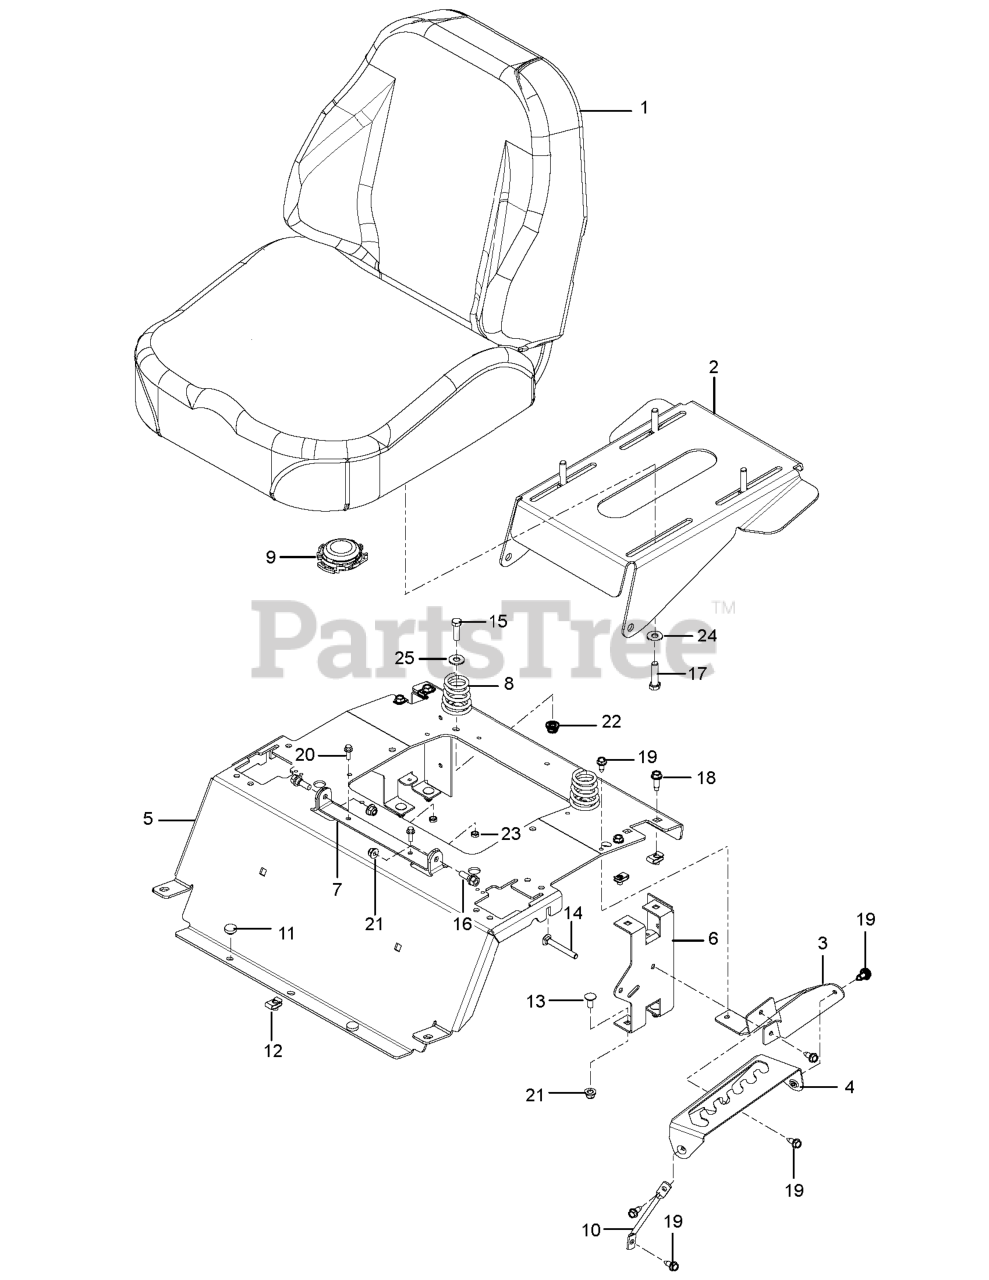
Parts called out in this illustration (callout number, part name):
1	Seat Bottom
2	PAN SEAT, 4-BOLT BLACK X428
3	PLATE.SUPPORT.DECK.LIFT.X431
4	PLATE.DECK.LIFT.X431
5	SUPPORT.SEAT.RZ.HUSQ.ORANGE
6	SUPPORT REAR SEAT BLACK
7	BRACKET.SEAT.REINF.X668
8	SPRING.COMPRESS.SEAT.TAPERED
9	SWITCH.SEAT.DELTA.OPC.
10	SUPPORT.LEG.DECK.LIFT
11	GROMMET.BUMPER
12	U-CLIP 5/16-18 NUT RETAINER
13	BOLT 5/16C X 3/4" CARRIAGE
14	RHSNB 5/16-18 X 2-1/2 GR5 ZD
15	BOLT
16	BOLT SHOULDER 5/16-18 UNC
17	BOLT.5/16-18X1-1/4 FULL.THREAD
18	SCREW.THDROL.5/16-18X3/4.TTY
19	BOLT.5/16HEX.WHS.HD
20	SCREW.FLG.LOCKING.1/4-20X.75
21	5/16-18 NYLOC FLANGE NUT
22	NUT 3/8-16 HEX FLG NYLOC ZD
23	NUT
24	WASHER
25	RP WASHER 3/8 FLAT
